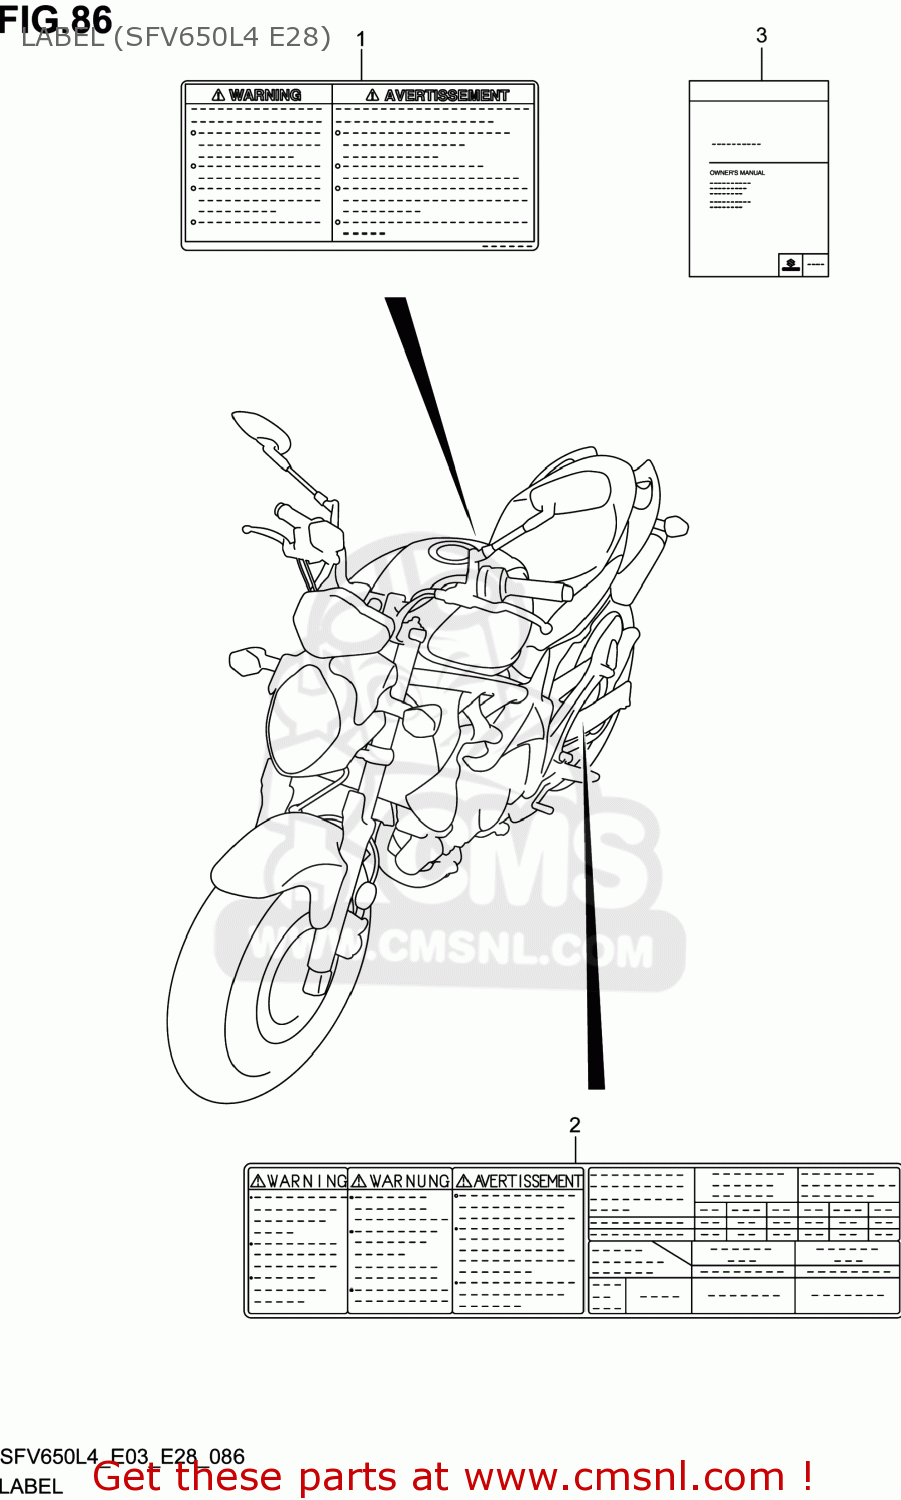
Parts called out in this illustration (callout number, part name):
1	LABEL,GENERAL WARNING
2	LABEL,TIRE INFORMATION
3	MANUAL,OWNER'S
